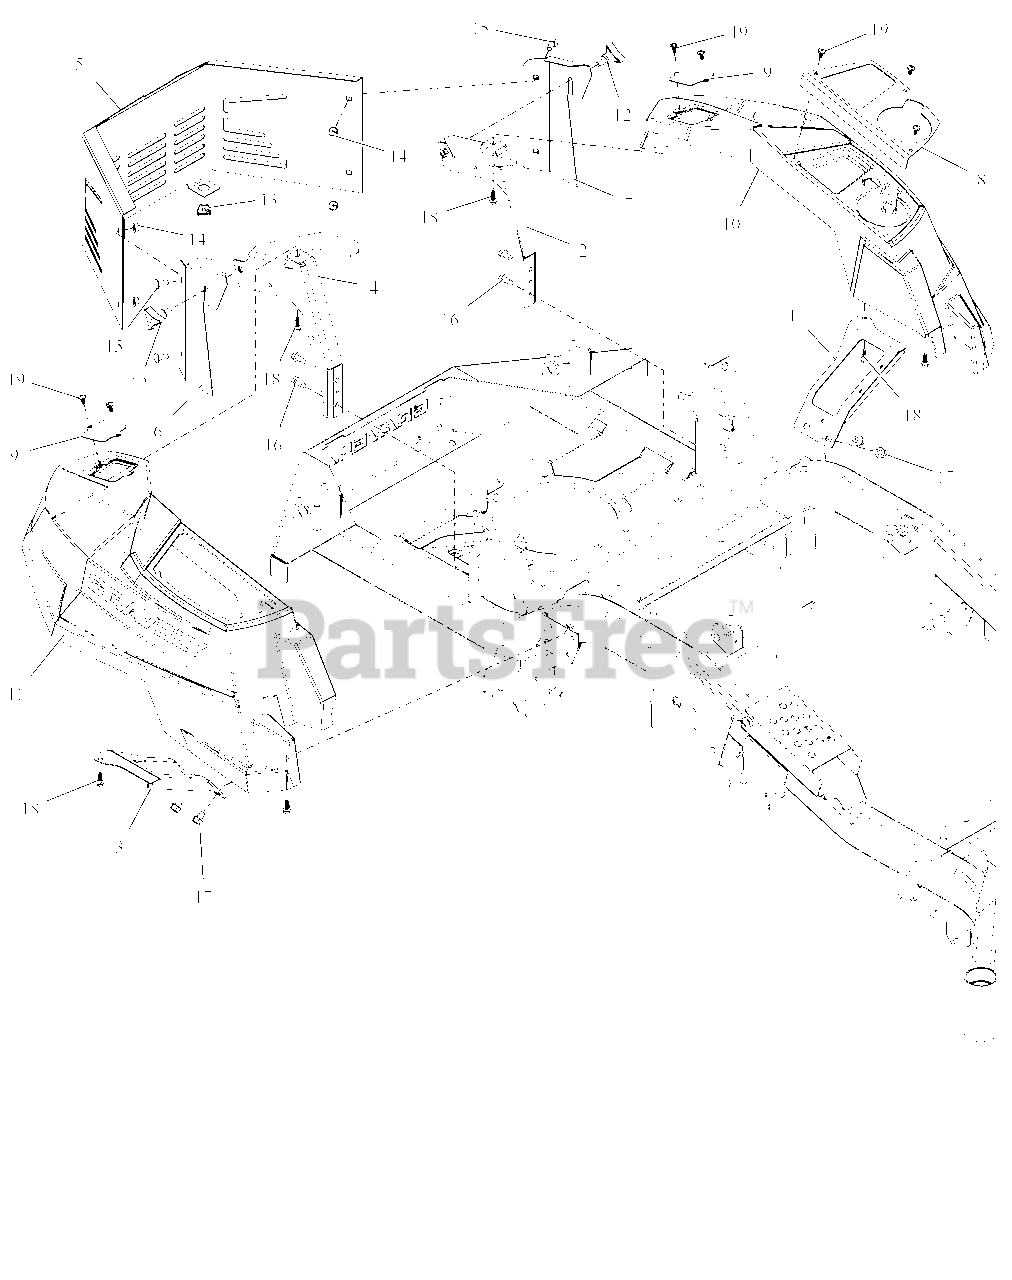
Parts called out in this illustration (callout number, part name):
1	WLDMT, LH FENDER MOUNT
2	BRKT, LH FENDER MTG
3	WLDMT, RH FENDER MOUNT
4	BRKT, RH FENDER MTG
5	GUARD, HD ENGINE
6	TRIM, HOOD STYLE (RIGHT)
7	TRIM, HOOD STYLE (LEFT)
8	PANEL, HD
9	PLATE, ROPS HOLE-HD
10	KIT, FENDER W/FUEL DECAL-HD
11	FENDER, RH HD (2017) SHRT BOSS
12	KNOB,WING STUD 5/16-18 X .75
13	GROMMET, 10MM BOLLHOFF
14	NUT,LK-CTR-FLG .31-18 GF ZCC
15	BLT, RHSSN.31-18X.750 G5 ZCC
16	SCR,TAP .312-18X.75 HWH TR ZCC
17	SCR,TAP .375-16X.50 HWH TR ZCC
18	SCR, PLASTITE-HWH 0.25 X 0.75 ZC120
19	SCR-PAN .25-15X.50 6L H/LZB500
